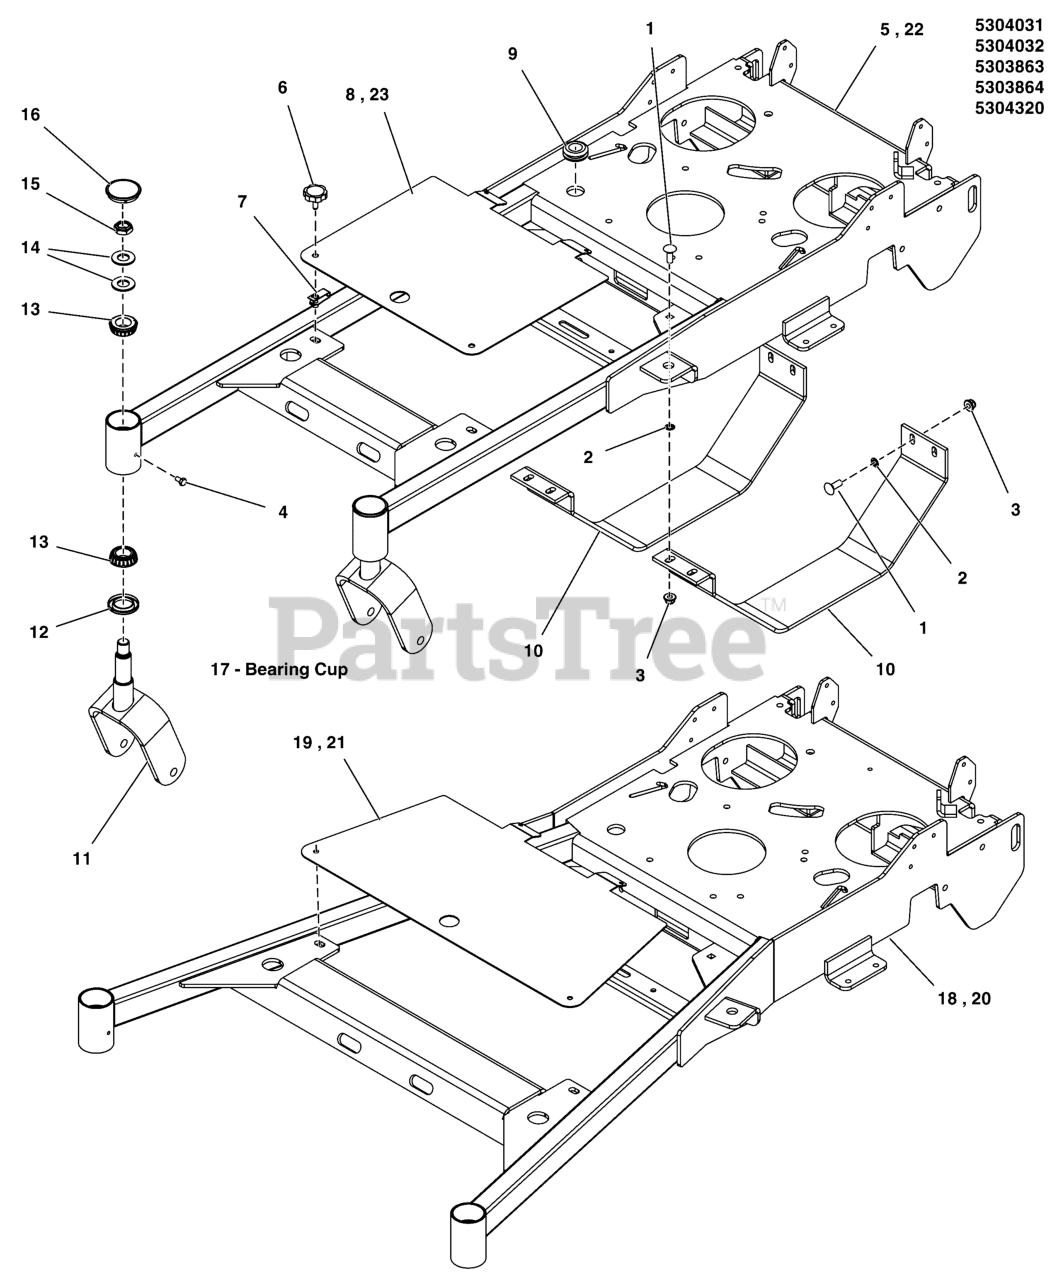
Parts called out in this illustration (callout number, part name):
1	BOLT,3/8-16X1.000,RND HD CRRG,ZINC/CLEAR
2	3/8 PUSHNUT BOLT RETAINER
3	NUT, 3/8-16 HEX NYLOCK FLANGE
4	BOLT, 1/4-28 X 1/2, GD5 CZ
5	WELD, MAIN FRAME, W25 - 36 - RED
6	KNOB, 5/16-18 X 1.00, ROSETTE, BLK
7	BODY CLIP, 5/16-18 -1/4 MATERIAL
8	GUARD, WALK, FRONT FRAME, 36 - RED
9	GROMMET, 7/8"ID, 1/4" THICK STK
10	PLATE, TRANS GUARD SW25 - BLK
11	WELD, CASTER YOKE, SNP DD - RED
12	SEAL, GREASE
13	BEARING, TAPERED ROLLER, 1
14	WASHER, BELLEVILLE - 1.500 X .755
15	NUT, 3/4-16, HEX JAM NYLON LOCK
16	CAP, GREASE, LOW PROFILE
17	BEARING, CUP
18	WELD, MAIN FRAME, W25 - 48 - RED
19	PLATE, FRONT FRAME GUARD W25 48 - RED
20	WELD, MAIN FRAME, W25, 48/52 - RED
21	PLATE, GUARD, FRONT FRAME, W25 48/52 - RED
22	WELD, MAIN FRAME, W25, 36 - RED
23	PLATE, FRAME GUARD, W25 36 - RED
